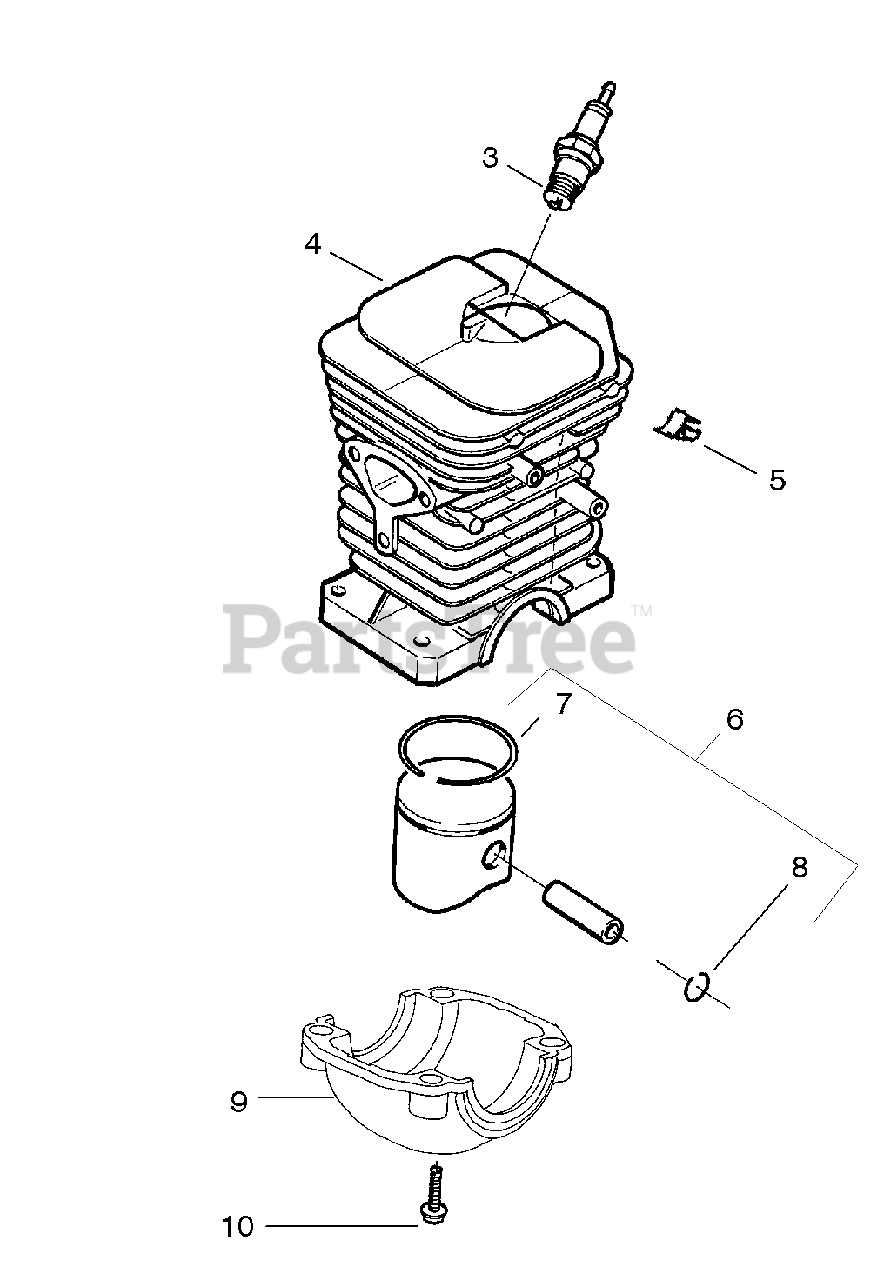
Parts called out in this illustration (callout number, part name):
3	Spark Plug
4	Kit-Cylinder
5	Clip - High Tension Lead
6	Kit-Piston
7	Ring-Piston
8	Piston Pin Retainer
9	Cap-Crankcase
